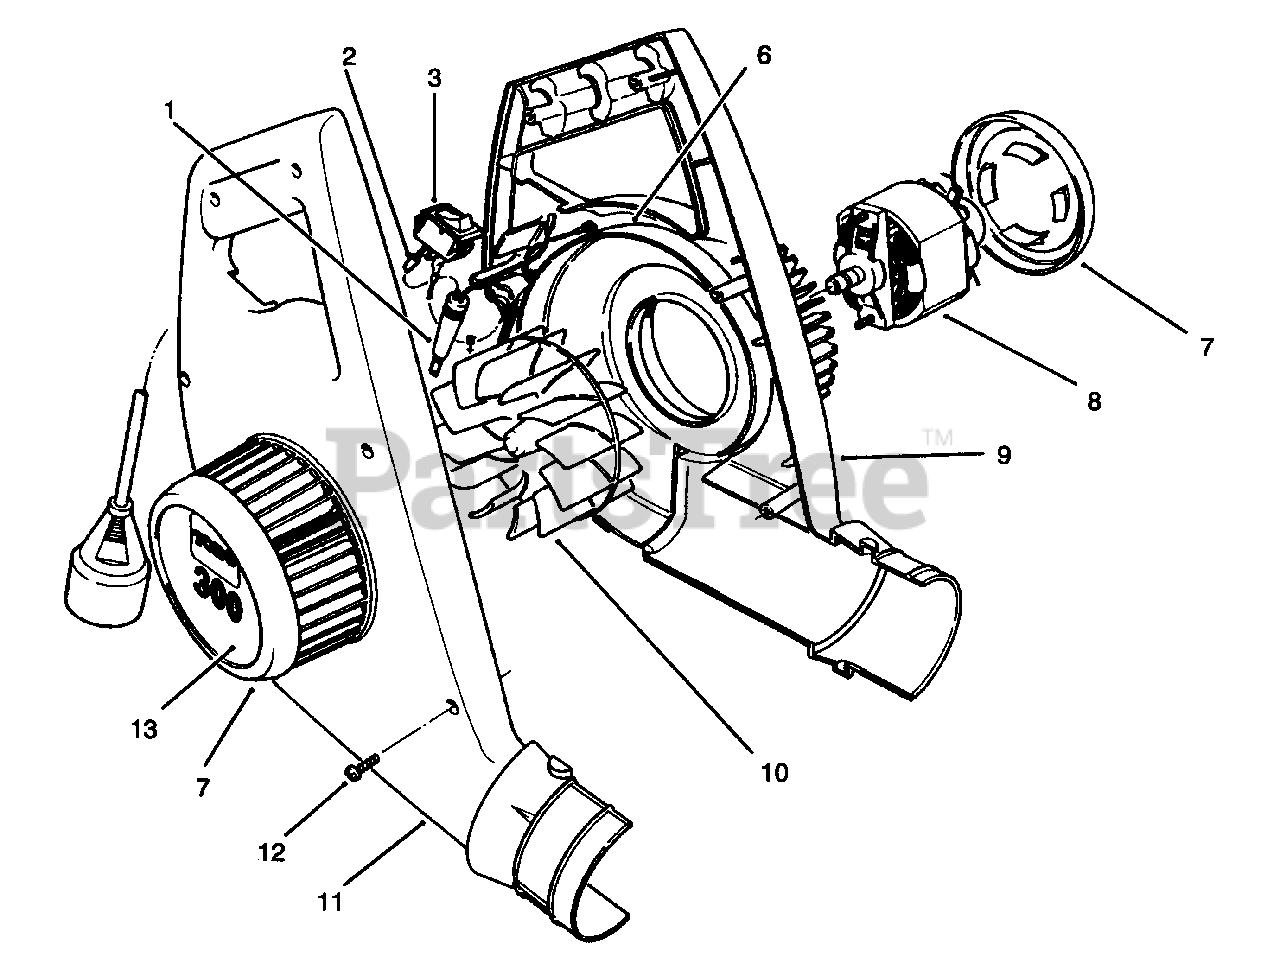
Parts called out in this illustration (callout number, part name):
1	Cord-Power Supply
2	Connector
6	Cover-Motor
7	Cover-Intake
8	Motor-120 Volt
9	Housing-L.H.
10	Impeller
11	Housing-R.H.
12	Screw-Thread Forming
13	Decal-300
